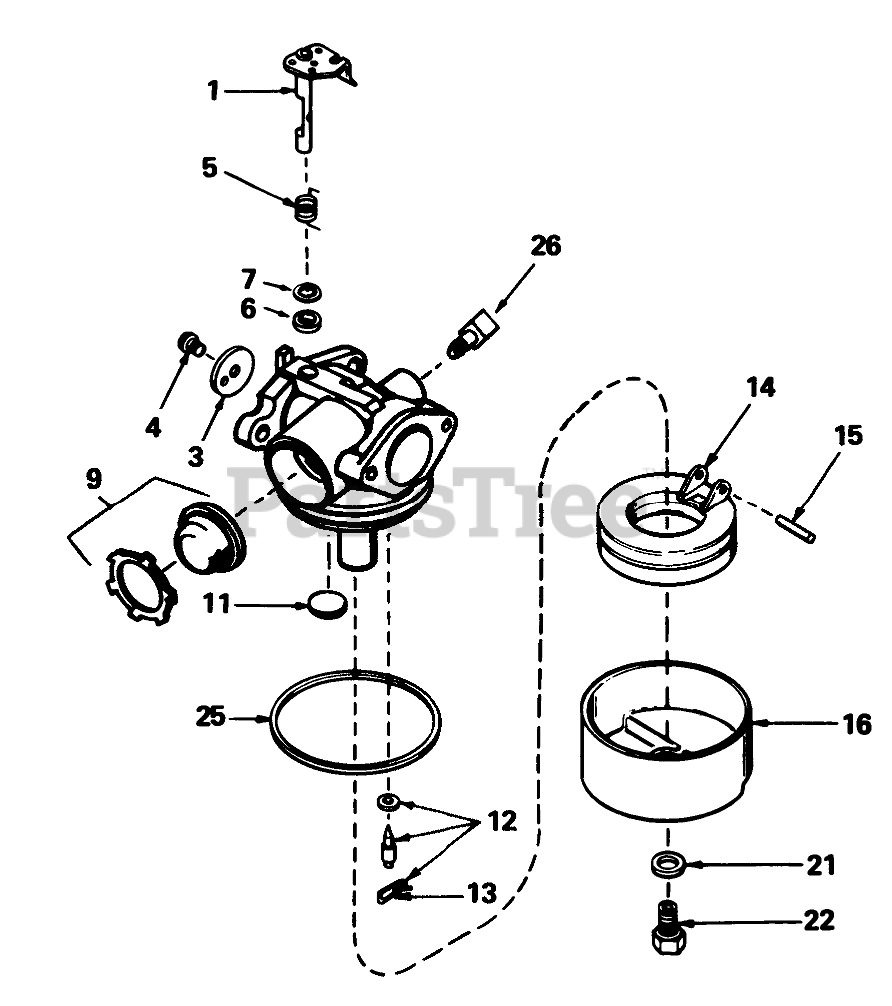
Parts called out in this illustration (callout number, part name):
1	Throttle Shaft and Lever ASM
3	Throttle-Shutter
4	Screw-Shutter
5	Spring-Return, Throttle
6	Seal-Dust
7	Washer-Seal, Dust
9	Primer Assy.
11	Plug-Welch, Atmospheric Vent
12	Inlet Needle-Seat & Clip Assy. (Incl. Ref. #13)
13	Clip-Spring
14	Float
15	Shaft-Float
16	Bowl Float
21	Gasket-Bowl
22	Nut-Float Bowl
25	O Ring-Bowl, Float
26	Fitting-Fuel
